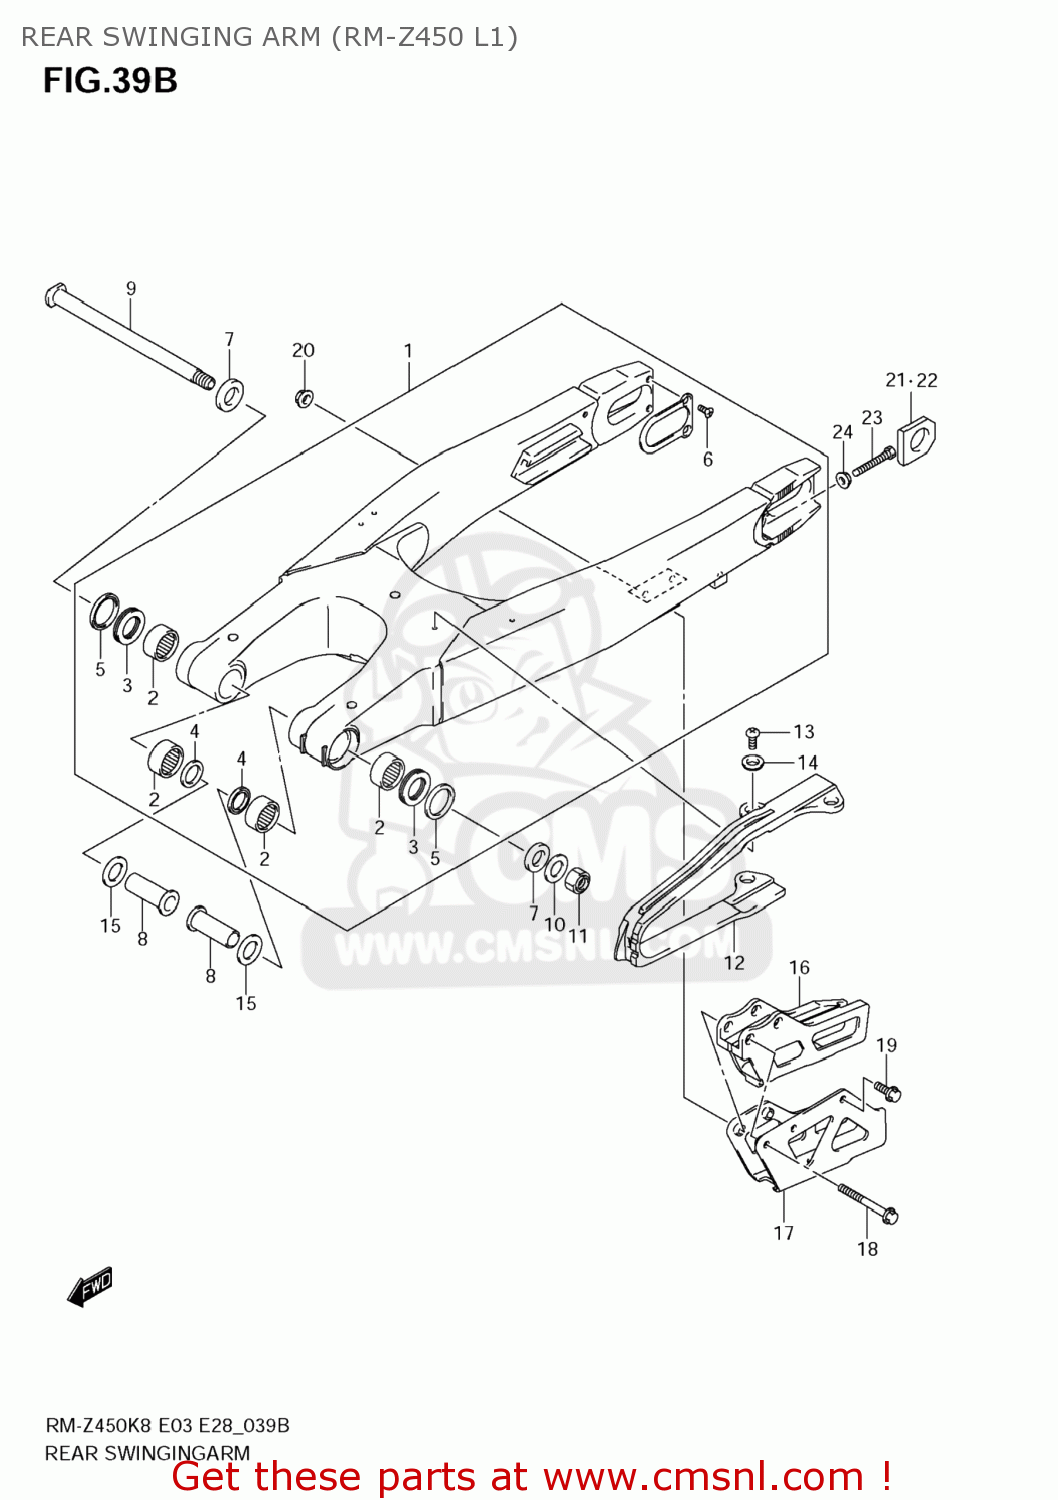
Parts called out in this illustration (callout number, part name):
1	SWGARM ASSY,RE
2	BEARING(22X29X15)
3	BEARING(22X35X2)
4	SEAL,OIL(22X29X4)
5	SEAL,RR SWGARM PIVOT OUTER
6	SCREW
7	SPACER,RR SWGARM PIVOT OUTER
8	SPACER,SWGARM PIVOT INNER
9	SHAFT,RR SWINGINGARM PIVOT
10	WASHER
11	NUT
12	BUFFER,CHAIN TOUCH DEFENSE
13	SCREW
14	WASHER
15	WASHER
16	GUIDE,CHAIN
17	PLATE,CHAIN GUIDE
18	BOLT(6X45)
19	BOLT(6X12)
20	NUT
21	WASHER,CHAIN ADJUSTER,R
22	WASHER,CHAIN ADJUSTER,L
23	BOLT(8X50)
24	NUT
